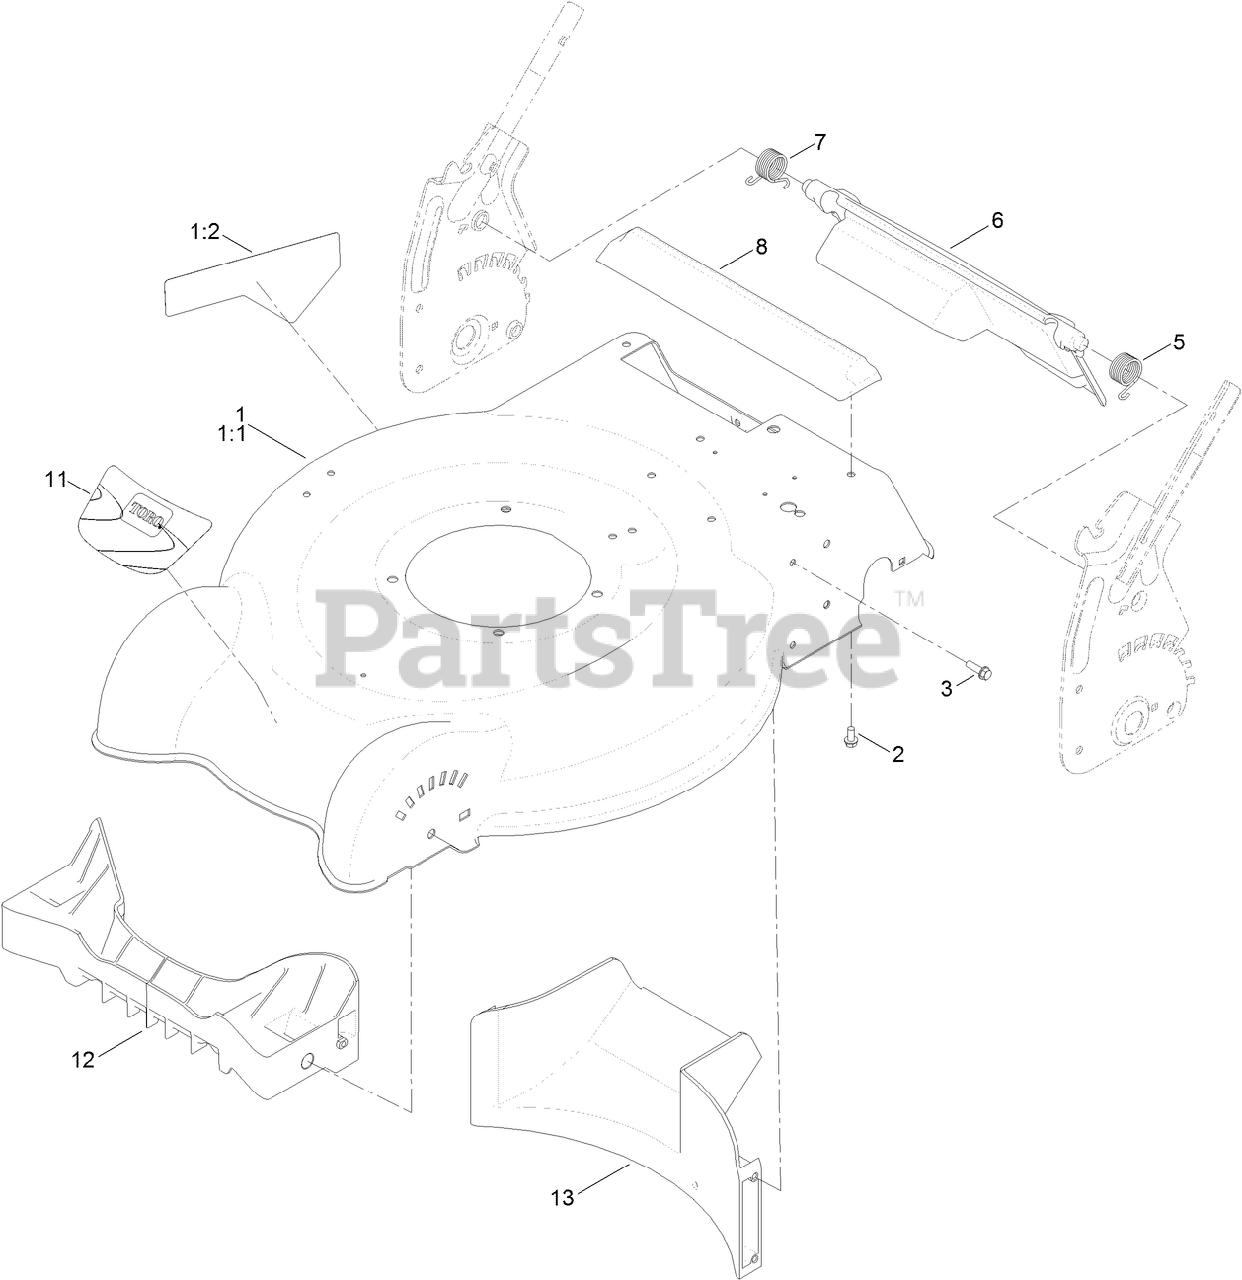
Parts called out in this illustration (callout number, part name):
1	ELECTRIC HOUSING ASM
1:1	DECK-20 INCH
1:2	DECAL-DANGER
2	SCREW-PLASTITE
3	SCREW-HWH
5	SPRING-TORSION, LH
6	DEFLECTOR-REAR
7	SPRING-TORSION, RH
8	CHUTE-REAR
11	DECAL-BATTERY
12	BAFFLE-THROW, FRONT
13	BAFFLE-REAR
